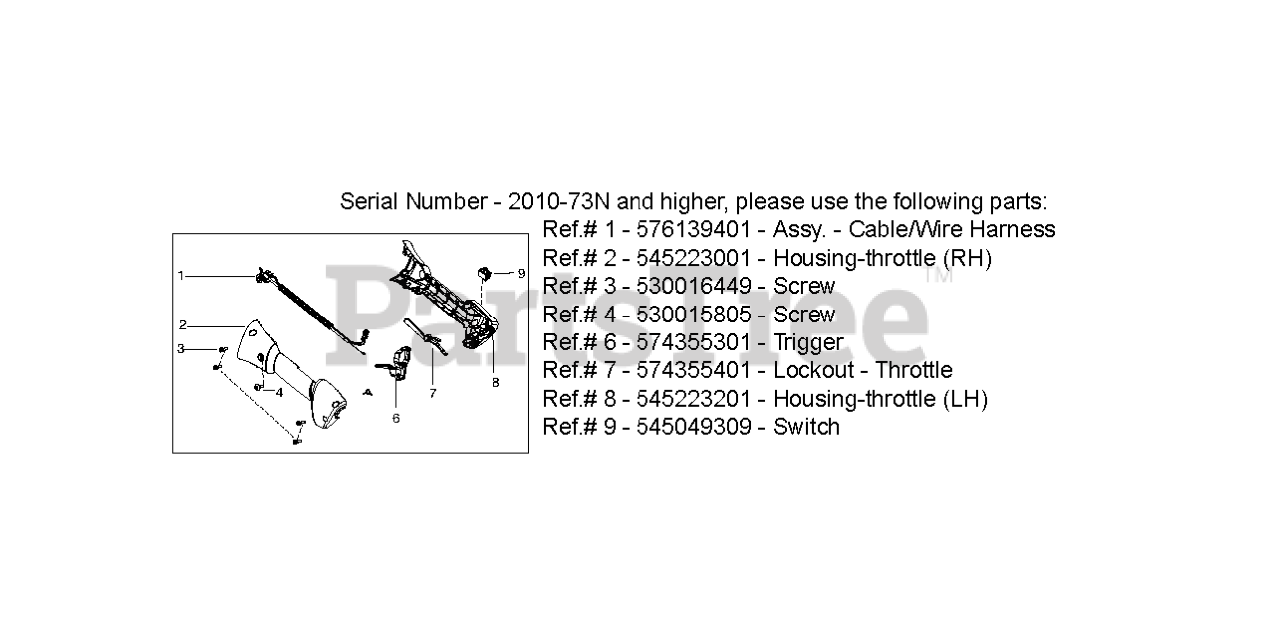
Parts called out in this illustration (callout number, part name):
1	ASSY CABLE / WIRE HARNESS
2	HSG THROTTLE RIGHT HVA
3	SCREW M4 X 1.75 PT 16MM
4	SCREW-10-14 X 1/2 PLASTITE
6	TRIGGER THROTTLE HVA ORANGE
7	THROTTLE LOCKOUT HVA ORANGE
8	HSG THROTTLE LEFT HVA
9	SWITCH
